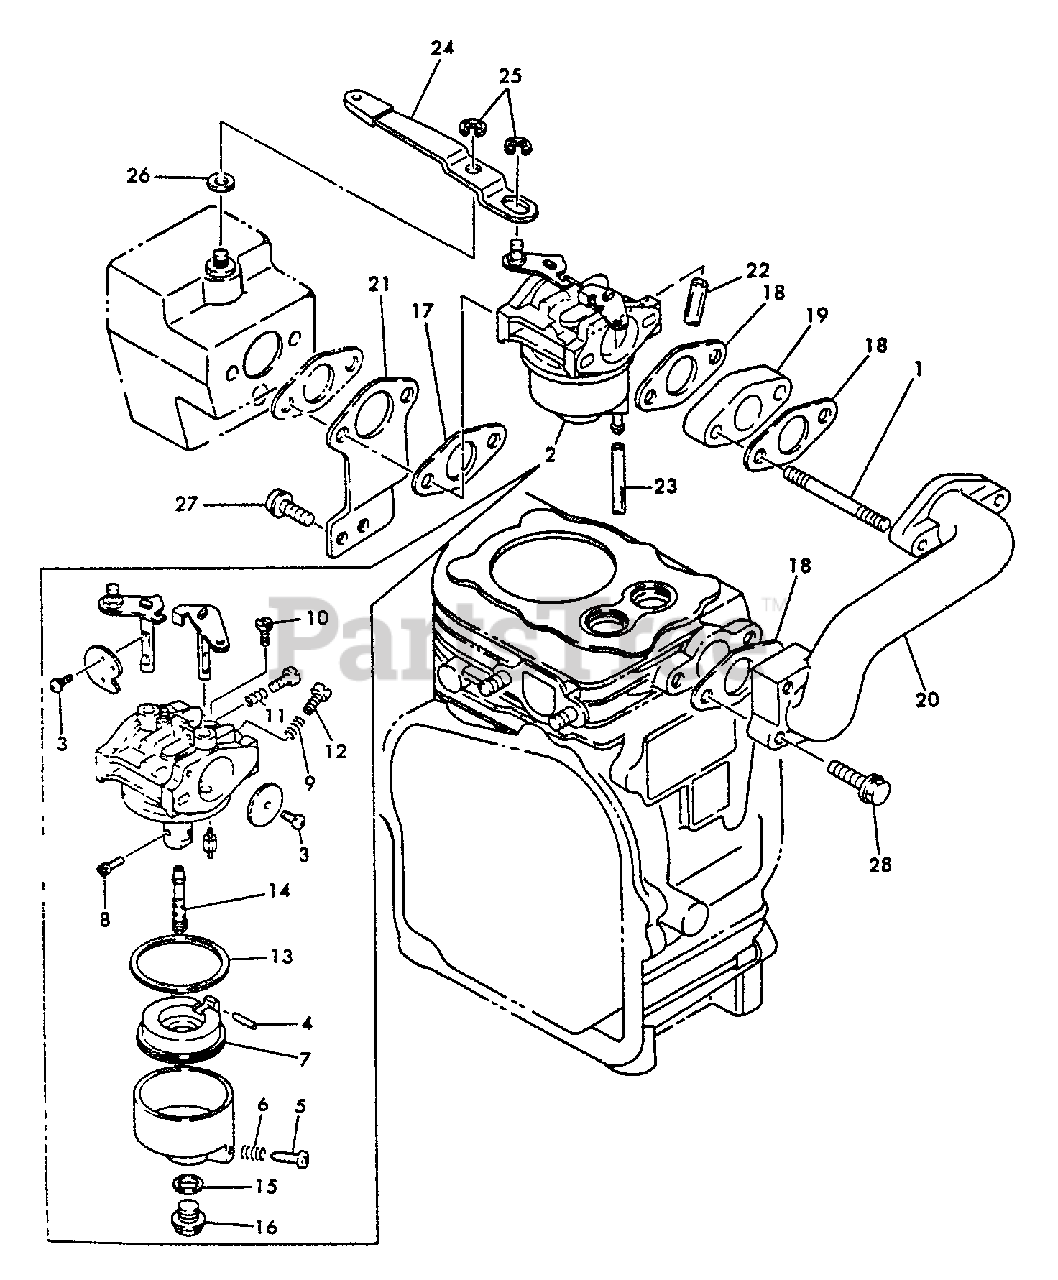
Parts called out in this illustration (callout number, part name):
1	PIN
2	CARBURETOR
3	SCREW
4	PIN
5	SCREW
7	FLOAT ASSY
8	JET, MAIN
10	JET, PILOT
12	SCREW, ADJUST
13	GASKET
14	NOZZLE, MAIN
15	WASHER
16	BOLT
17	GASKET, INTAKE
18	GASKET, INTAKE
19	SPACER, MANIFOLD
20	MANIFOLD, INTAKE
21	SUPPORT
22	PIPE
23	HOSE
24	LEVER, CHOKE
25	RING, RETAINING - 5
26	WASHER - 6 -- NYLON
27	SCREW - 6X12
28	BOLT - 6X25
